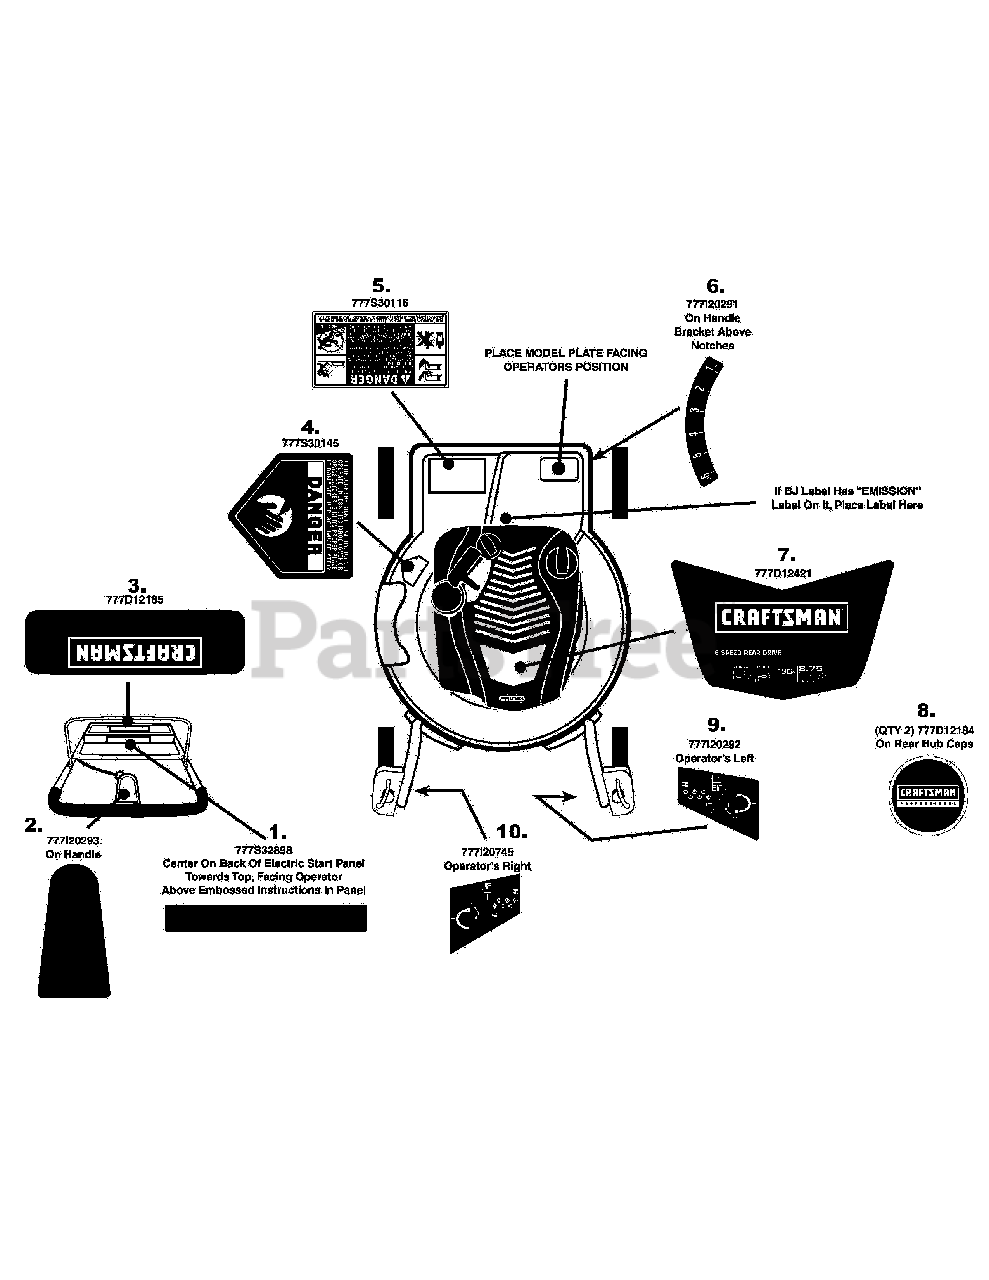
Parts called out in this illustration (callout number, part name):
1	LABEL-MOWER CHARGE CAUTION
2	LABEL-6SPD SELF PROPLD
3	LABEL-MOWER CRAFTSMAN PRO
4	LABEL
5	LABEL-MOWER DANGER
6	LABEL-HEIGHT ADJUS
7	LABEL-MOWER SHROUD CRAFTSMAN PRO
8	LABEL-MOWER HUB CRAFTSMAN PRO
9	LABEL-CASTOR LOCK
10	LABEL-CASTOR LOCK
